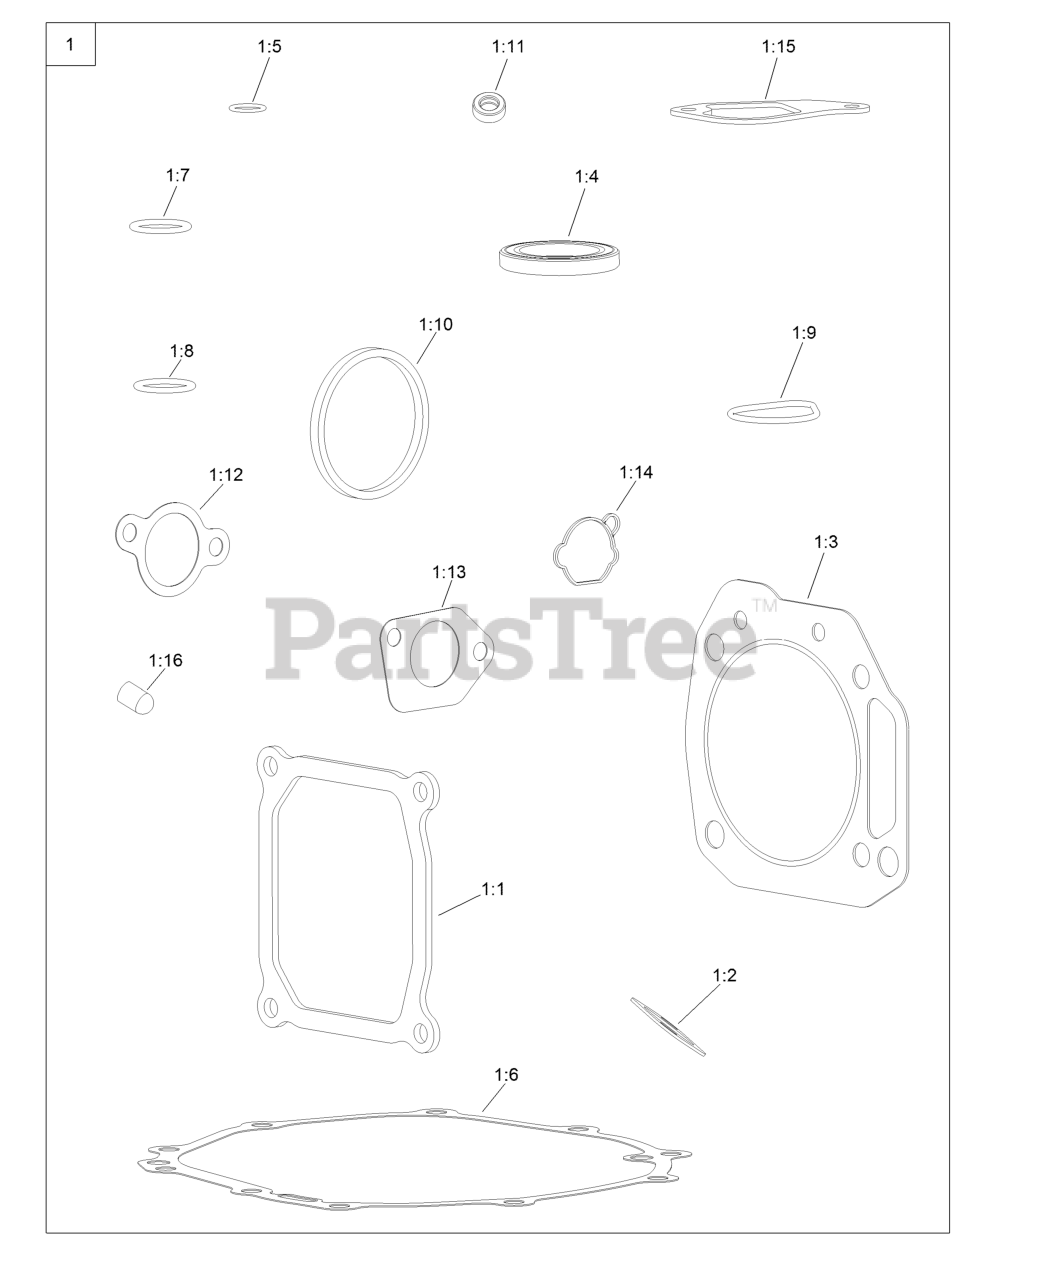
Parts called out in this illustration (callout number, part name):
1	GASKET AND SEAL KIT
1:1	GASKET-COVER, VALVE
1:2	GASKET-EXHAUST
1:3	GASKET-CYCLINDER
1:4	SEAL-OIL
1:6	GASKET-CRANKCASE
1:9	SEAL-PUMP, OIL
1:10	SEAL-ADAPTOR, OIL
1:11	SEAL-OIL
1:12	GASKET-CARBURETOR
1:13	GASKET-CARBURETOR
1:14	GASKET-CARBURETOR
1:15	GASKET-BREATHER
1:16	CAP-SEAL
